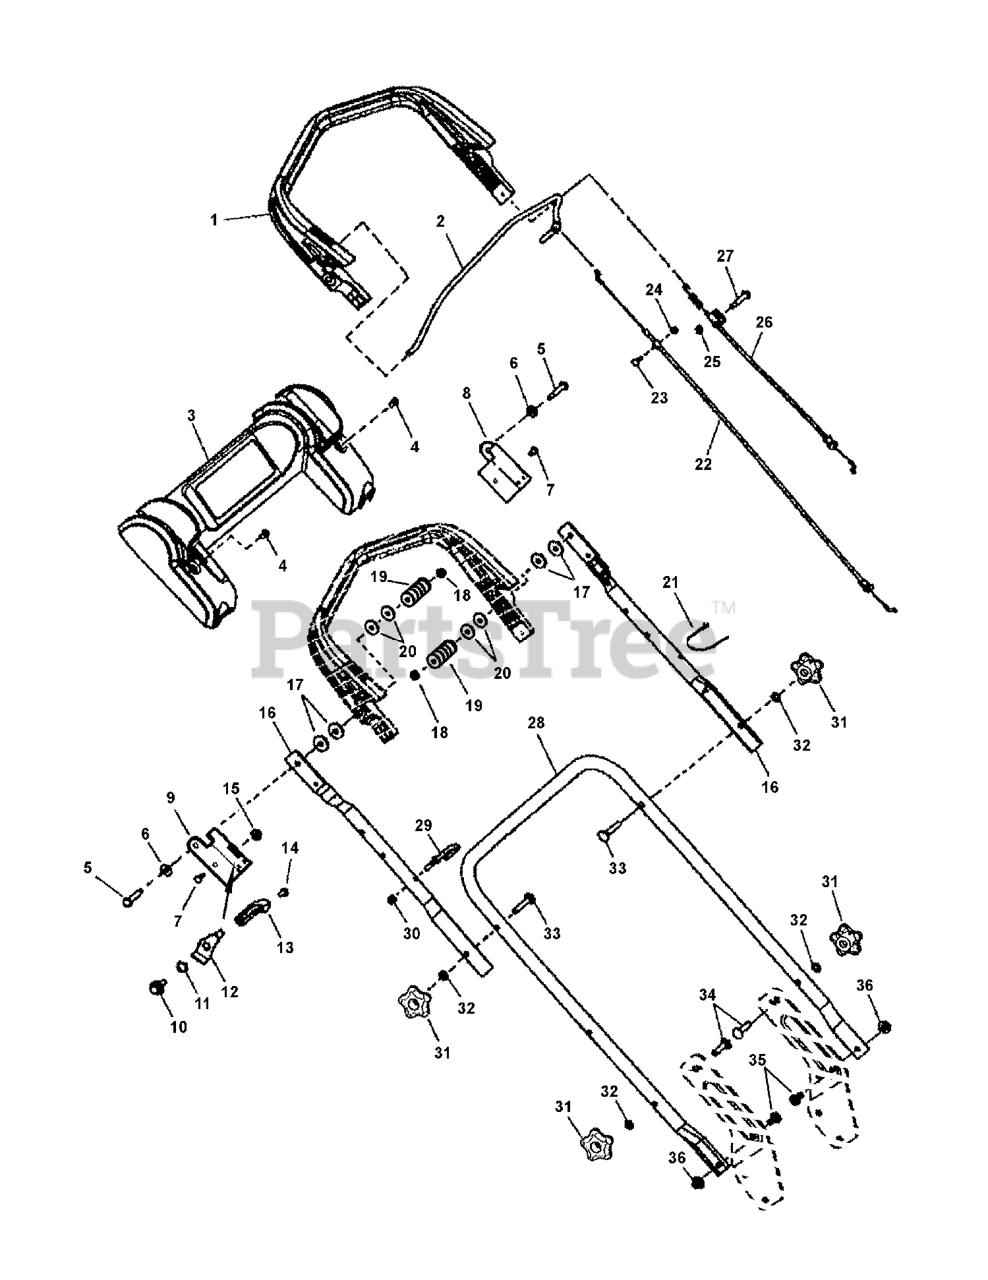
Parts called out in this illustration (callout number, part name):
1	HANDLE, PIVOTING - DEERE WALK
2	BAIL, PIVOTING HANDLE - 21" JD WBM
3	PANEL, UPPER HANDLE, DEERE
4	RIVET, POP.250D .6L AL, STL STEM-BLACK
5	BOLT, SHOULDER, 5/16 X 2.500, YZ
6	SHIM WASHER, 5/16 I.D.
7	TORX ST, 1/4-20 X .550
8	BRACKET, LH, ROTATION LIMIT
9	BRACKET, RH, ROTATION LIMIT
10	IDLER PIVOT BOLT
11	WASHER, .531 X .781 3-WAVE
12	HANDLE, LOCK
13	THROTTLE CONTROL LEVER
14	RIVET, PLASTIC SNAP
15	FLN, 5/16-18 YZ
16	HANDLE, UPPER, STRAIGHT, EASY LINE
17	WASHER, FLAT, 1" OD X .387 ID
18	NUT, HEX FLANGE,1/4-20, ESNA,YZ
19	SPRING, COMPRESSION
20	FW, .33X.88X.09
21	WIRE TIE,11 INCH STD BLK NYLON
22	CABLE, BAIL, 2010 WBM
23	RHSNB, 10-24X3/4, YZ
24	HLN, 10-24 UNC-2B W/NYLON INSERT
25	HCLN, 1/4-20
26	CABLE, DRIVE, VS, FWD, JD
27	HHCS, 1/4CX1-3/4
28	HANDLE, LOWER 21" RD, JD
29	GUIDE, ROPE
30	HN, 1/4C NYL RNG
31	KNOB, HANDLE, 5 PRONG
32	ITLW 5/16
33	CHSNB, 5/16-18 X 2 GR2
34	BOLT, RD HD SH SQ NK 5/16-18X1.500 G5 YZ
35	RHSSNB, 5/16-18 X 3/4 GR5 YZ
36	LHCLN, 5/16-18- BLACK
